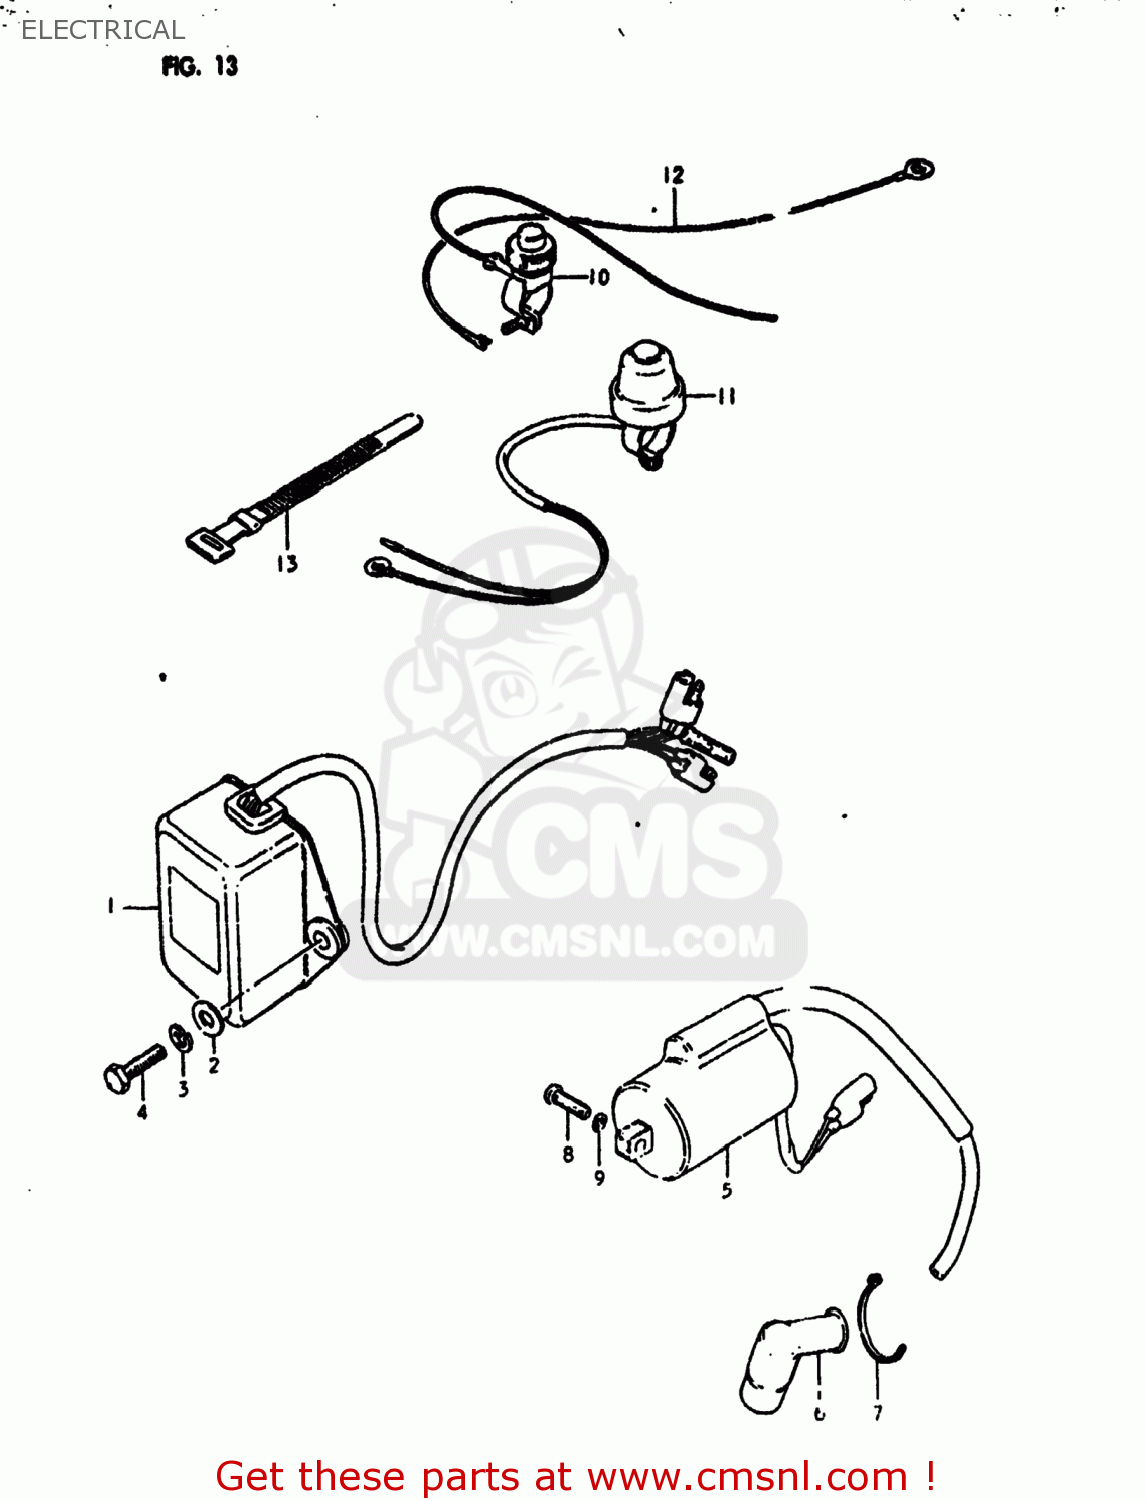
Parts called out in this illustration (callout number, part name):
1	CDI UNIT ASSEMBLY
2	WASHER(6.5X16X1.2)
3	LOCK WASHER
4	BOLT
5	COIL ASSEMBLY,IGNITION
6	CAP,SPARK PLUG
7	CLAMP
8	SCREW 5X20
9	LOCK WASHER
10	SWITCH ASSEMBLY
11	SWITCH ASSEMBLY
12	WIRE,ENGINE STOP EARTH
13	CLAMP(L:120)
